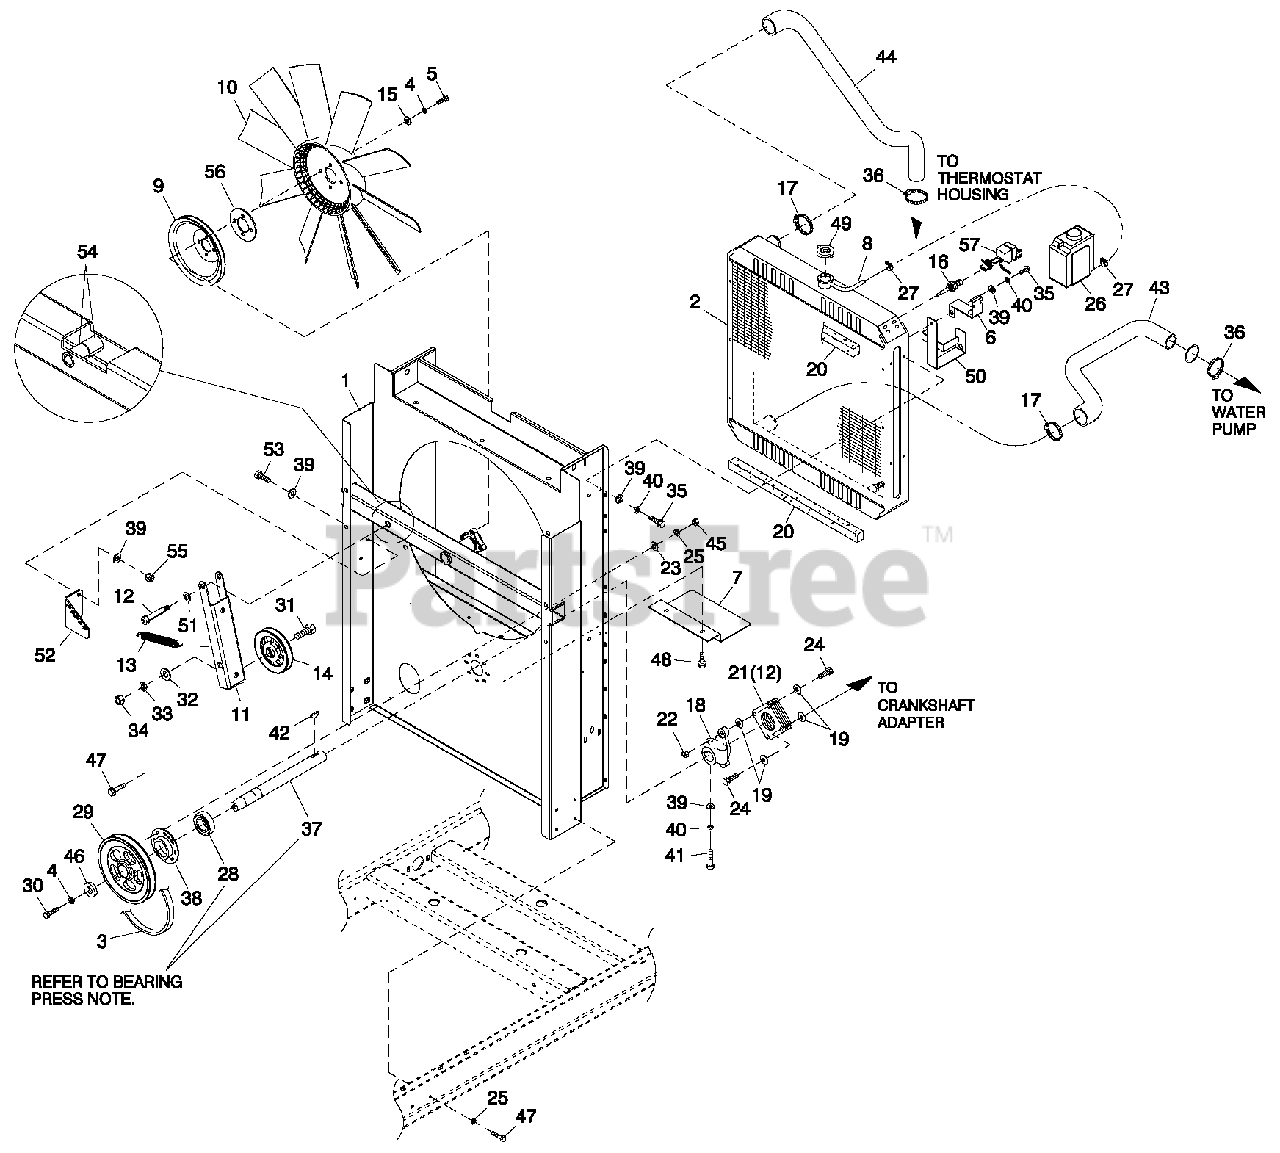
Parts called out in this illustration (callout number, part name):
1	WELDMENT RADIATOR SUPPORT C2
2	RADIATOR 598 X 568 X 49 CPL RH
3	V-BELT 31/64" X 57-3/8"
4	WASHER LOCK M10
5	SCREW HHC M10-1.5X30G10.9
6	BRACKET, SIGNAL CONDITIONER (USED ONLY WITH QTA PRODUCT)
7	SHIELD RADIATOR C4
8	HOSE 9/32 ID (27"LG)
9	PULLEY FAN V-GROOVE 9"
10	FAN COOL 22" DIA10 BLADE LH
11	ARM BELTTENSIONER
12	SHOULDER BOLT 1/2 X 2-1/4"
13	SPRING TENSION CPL
14	PULLEY V-BELT 4" FLANGED
15	WASHER FLAT 3/8-M10 ZINC
16	PROBE, COOLANT LEVEL 3/8NPTF
17	CLAMP HOSE #28 1.32-2.25
18	HUB FLEX PLATE
19	WASHER FLEX (THIN)
20	TAPE FOAM 1 X 1 (26.75" LG)
21	DISK FLEX
22	NUT HEX LOCK 5/16-24 NY INS
23	WASHER FLAT 1/4-M6 ZINC
24	SCREW HHC 5/16-24X1.124
25	WASHER LOCK M6-1/4
26	TANK COOLANT RECOVERY
27	CLAMP HOSE BAND 1/4
28	BEARING #6205 2NSE C3 E SRI2 S
29	PULLEY 4.5" DIA MACHINED
30	SCREW HHCM10-1.5X30 G8.8
31	SCREW HHC 1/2-13X2" G8
32	WASHER FLAT 1/2 ZINC
33	WASHER LOCK 1/2
34	NUT HEX 1/2-13 STEEL
35	SCREW HHFC M8-1.25 X 20 W/M6
36	CLAMP HOSE #24 B1.06-2.00
37	SHAFT FAN DRIVE
38	RETAINER BEARING
39	WASHER FLAT 5/16-M8 ZINC
40	WASHER LOCK M8-5/16
41	SCREW HHC M8-1.25 X 45 C8.8
42	KEY WOODRUFF 4X19D
43	HOSE LOWER RADIATOR G2
44	HOSE UPPER RADIATOR G2 (USED WITH MANFLD P/N 0G0707)
45	NUT HEX M6X 1.0 G 8Y E L CHR
46	SPACER .5 X 1.5 X .25 STL/ZINC
47	SCREW HHFC M6-1.0X20G8.8
48	SCREW THF M6-1 X 16 N WA Z/JS
49	CAP RADIATOR 13 PSI
50	BRACKET COOLANT TANK
51	WASHER NYLON .50 X .87 X .06
52	BRACKET TENSIONER SPRING
53	SCREW HHC M8-1.25X20 C8.8
54	BEARING SLEEVE 1/2/ X 3/4 X 1
55	NUT HEX LOCK M8-1.25 NY INS
56	SPACER CPL COOLING FAN 1/8"
57	ASSY PCB LCL SENSOR (USE WITH I/N 16, P/N 0H1827 ONLY)
